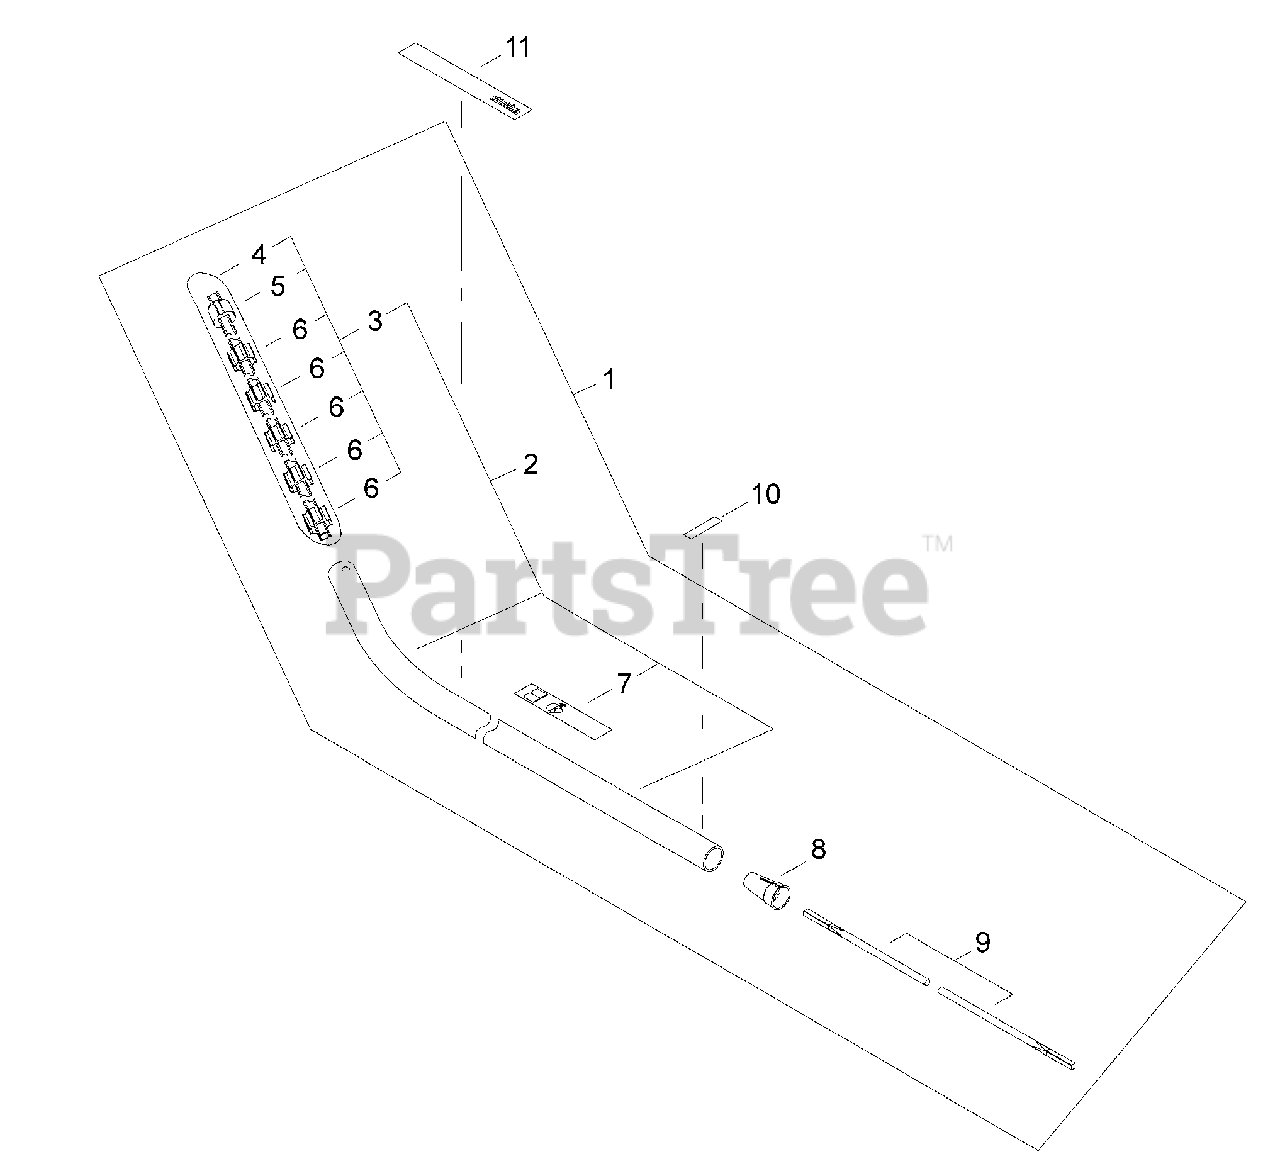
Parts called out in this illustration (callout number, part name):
1	MAIN PIPE & SHAFT ASSY
2	MAIN PIPE ASSY
3	LINER ASSY, PIPE
4	LINER - FLEXIBLE
6	BUSHING
7	LABEL, CAUTION
8	GUIDE, SHAFT
9	DRIVESHAFT - FLEXIBLE
10	LABEL, HANDLE
11	LABEL, SHINDAIWA PROFESSIONAL
